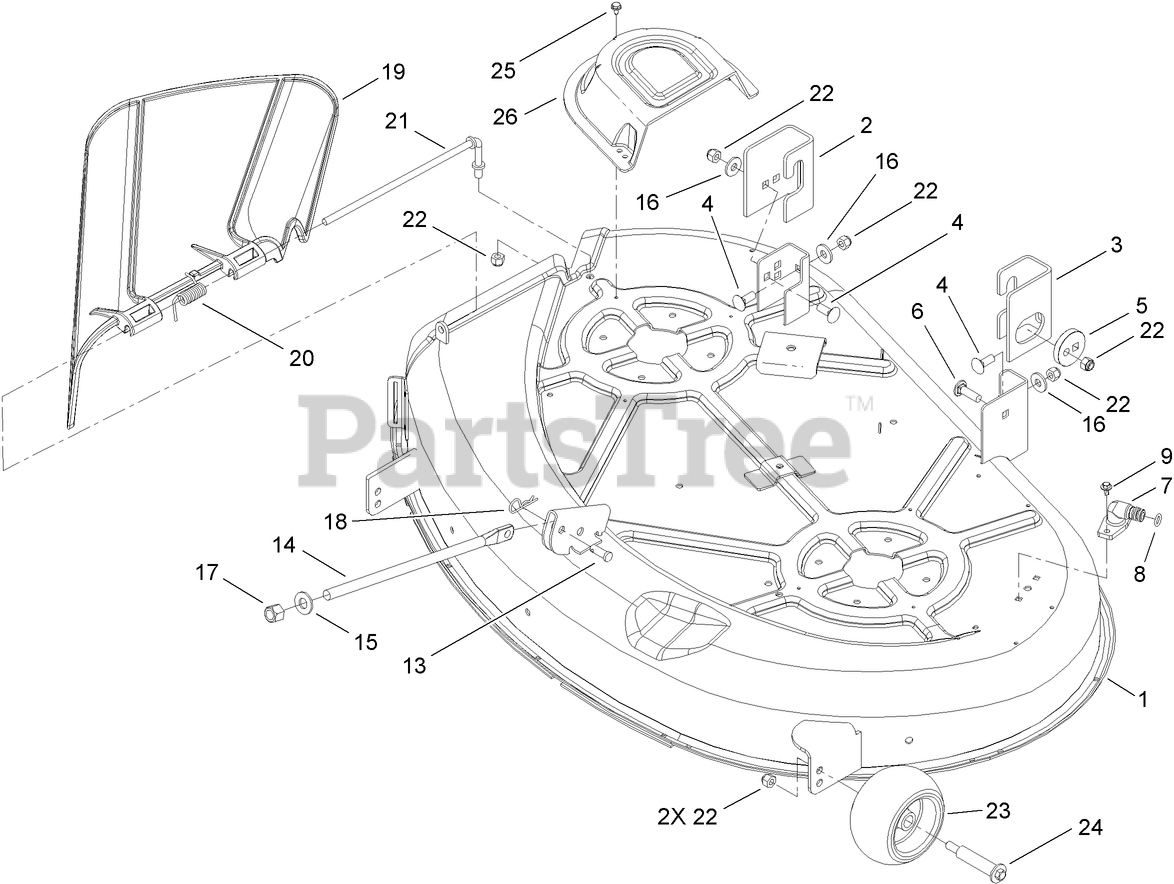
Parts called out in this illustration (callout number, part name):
1	42 INCH DECK ASM
2	BRACKET-HANGER, RIGHT REAR
3	BRACKET-HANGER, LEFT REAR
4	BOLT-CARR
5	ECCENTRIC
6	SCREW-CARR
8	O-RING
9	SCREW-HHFTF
13	PIN-CLEVIS
14	ROD-LIFT
15	WASHER-THRUST
16	WASHER-HARDENED
17	NUT-LOCK, NI
18	PIN-HAIR
19	DEFLECTOR
20	SPRING-TORSION
21	ROD-PIVOT
22	NUT-LOCK, NI
23	ROLLER-SCALP, ANTI
24	BOLT-SHOULDER
25	SCREW-HWHTF
26	COVER-BELT
